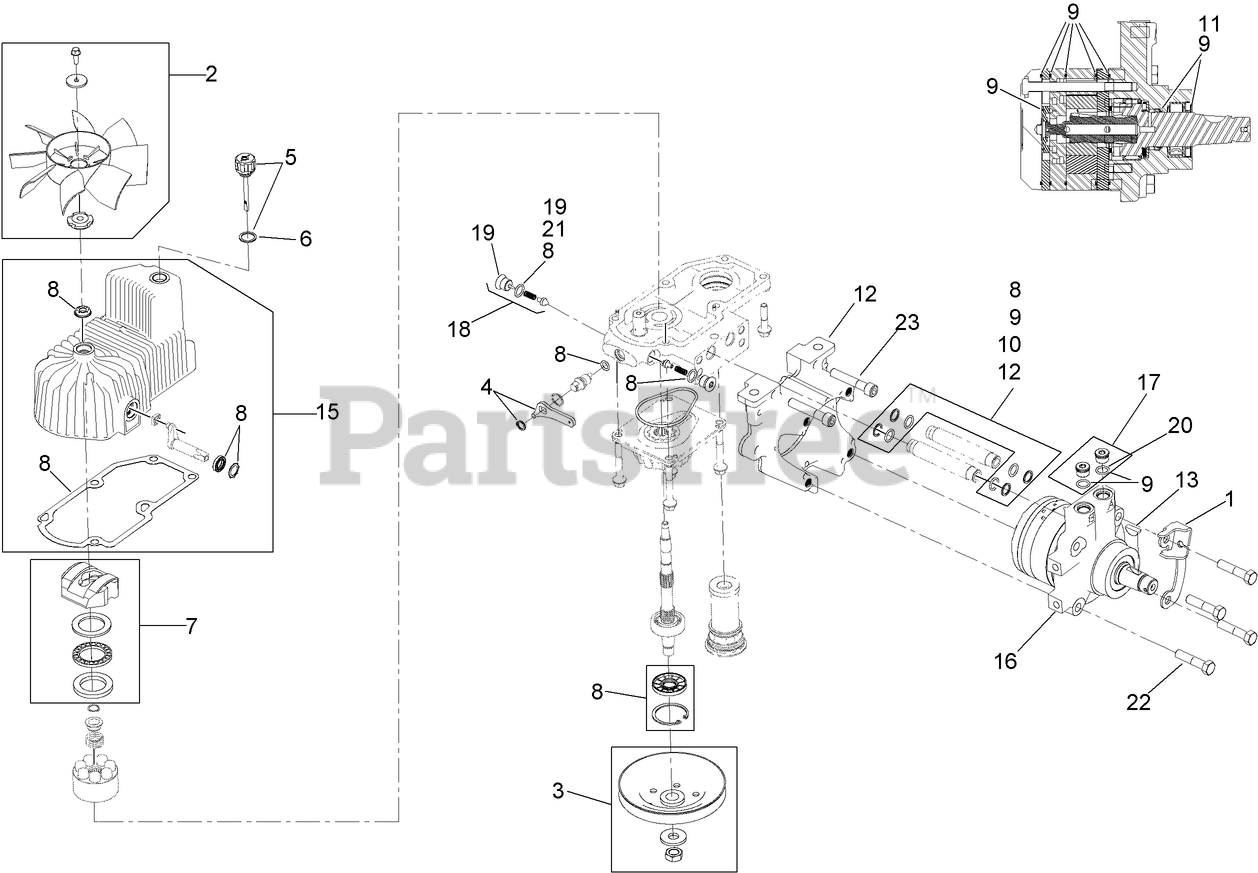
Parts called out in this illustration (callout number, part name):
1	BRACKET-ANCHOR, CABLE
2	FAN KIT
3	PULLEY KIT
4	HANDLE-BYPASS VALVE, HYDRO
5	DIPSTICK-HYDRO W/GASKET
6	GASKET-DIPSTICK, HYDRO
7	SWASH BLOCK KIT
8	PUMP SEAL KIT
9	MOTOR SEAL KIT
10	TUBE SEAL KIT
11	OUTPUT SHAFT SEAL KIT
12	NOSE CUP-UHT
13	Key-Woodruff 5/16 x 1
15	Housing-RH
16	MOTOR-HYDRAULIC RH 240CC
17	MAGNETIC PLUGS SERVICE KIT
18	CHECK VALVE ASM
19	PLUG-CHECK (W/O-RING)
20	O-RING
21	O-RING-CHECK VALVE
22	SCREW-HH 1/2-20 X 2 1/4
23	SCREW-HSH 1/2-20 X 2 3/4
